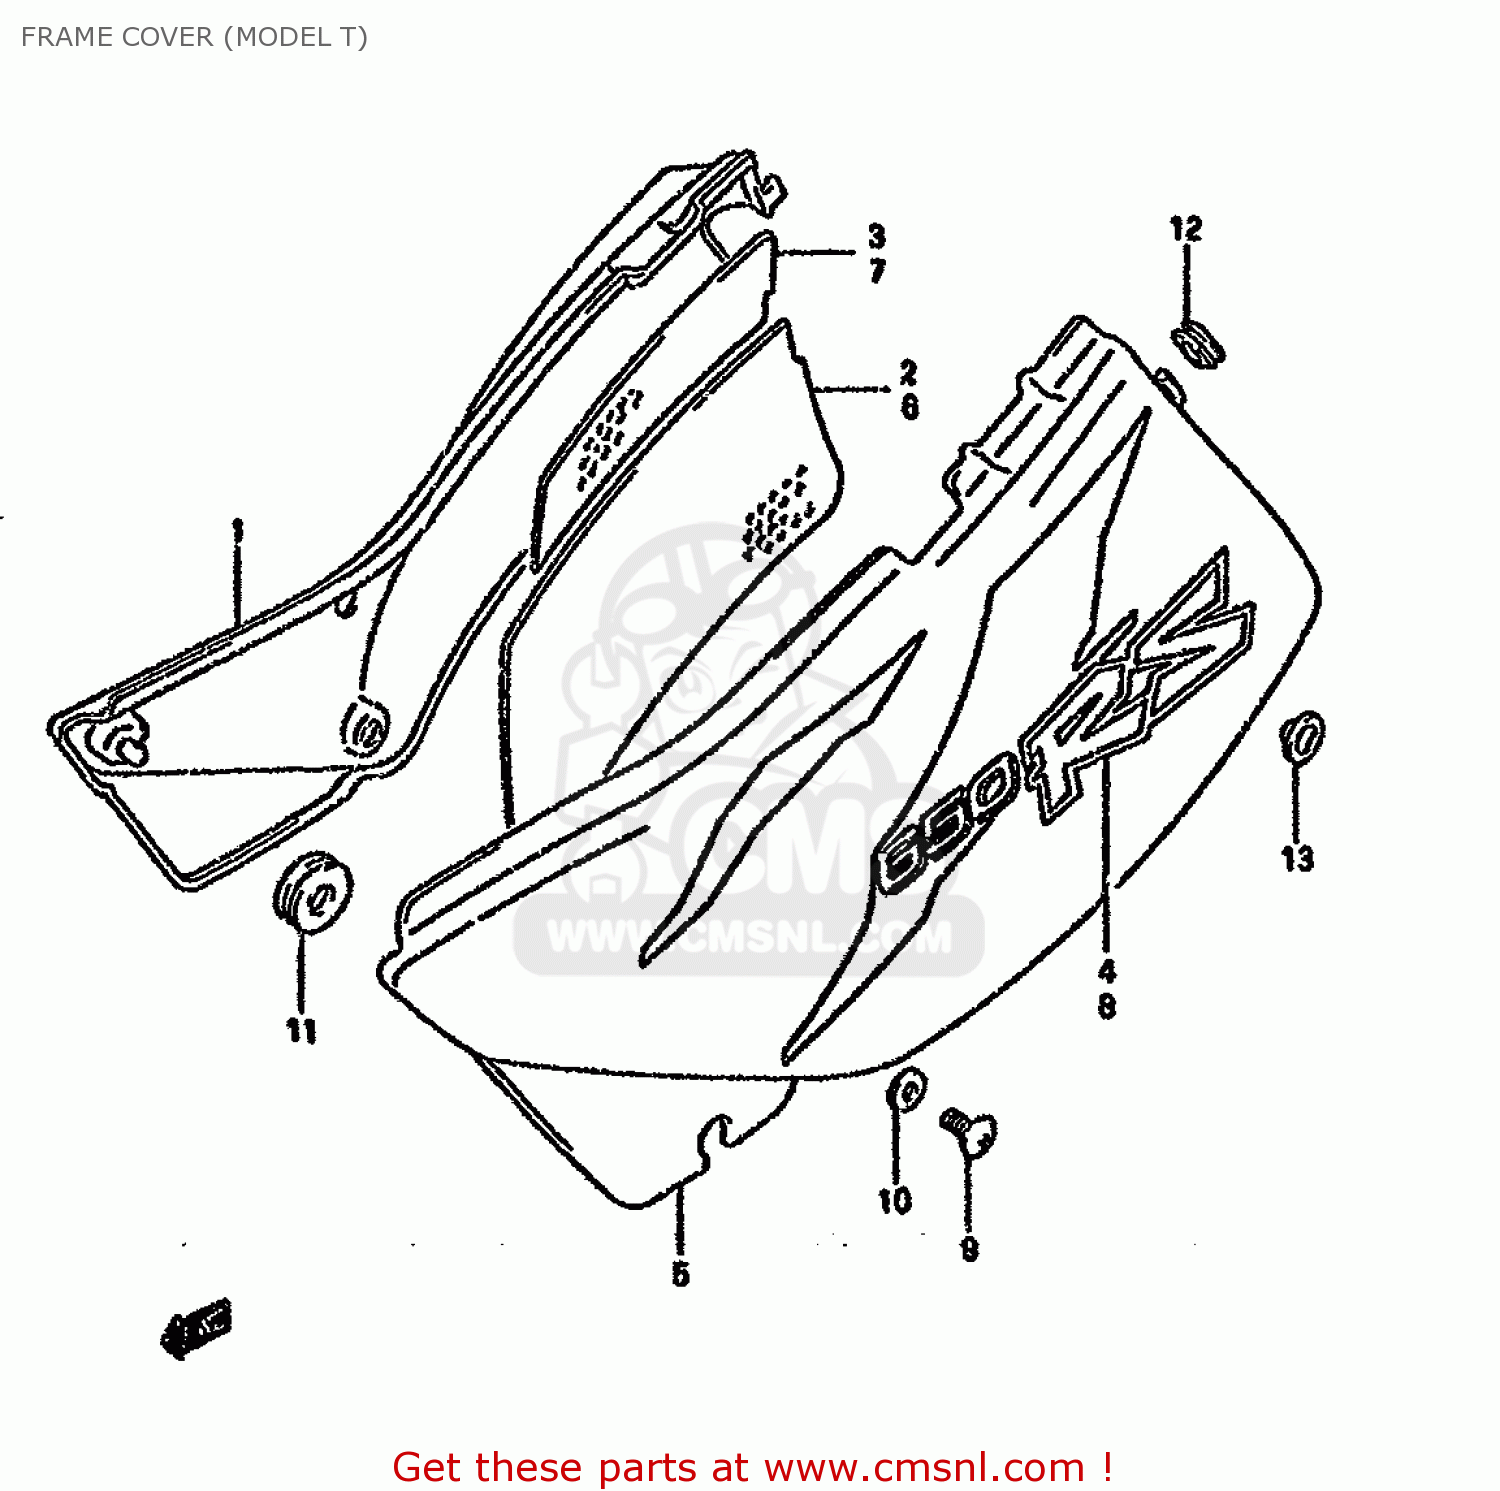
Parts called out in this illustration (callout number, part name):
1	COVER,FRAME,R(BLACK)
2	HEATSHIELD,LWR,R
3	SHIELD,FRAME C
4	TAPE,RH
5	COVER,FRAME,L(BLACK)
6	HEATSHIELD,LWR,L
7	SHIELD,FRAME COVER NO.2,L
8	TAPE,LH
9	SCREW 6X12
10	WASHER
11	CUSHION
12	CUSHION
13	CUSHION
